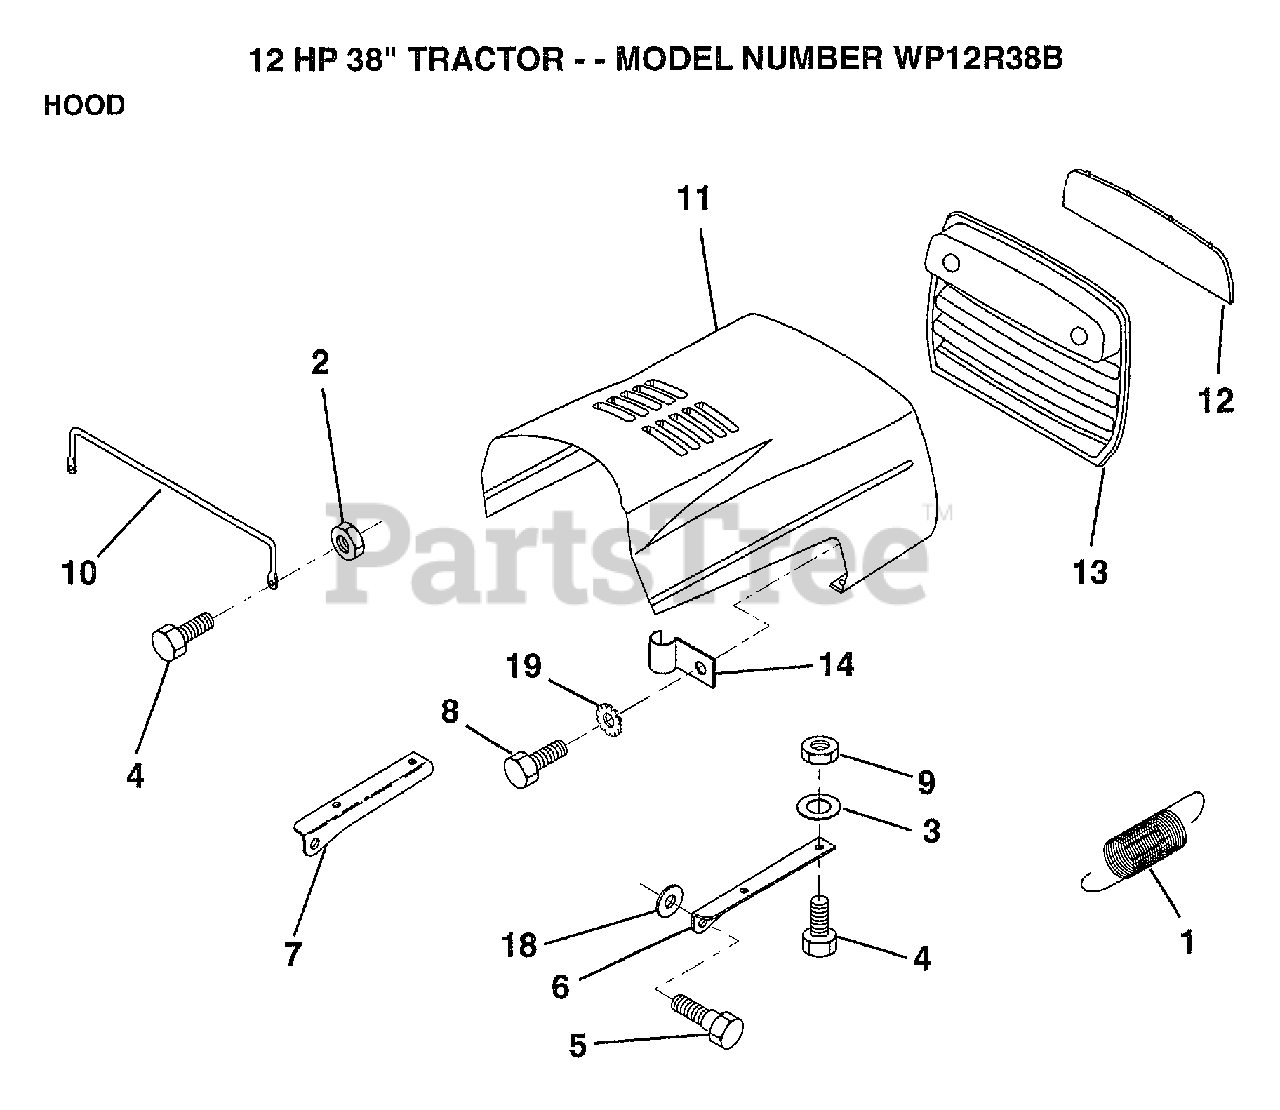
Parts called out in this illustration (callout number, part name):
1	EXT SPRING
2	NUT
3	WASHER
6	BRKT HOOD RH
7	BRKT HOOD LH
9	NUT
10	"BRACE,HOOD"
11	HOOD
12	LENS
13	GRILL
14	CLIP T
18	WASHER
19	LOCKWASHER GT
